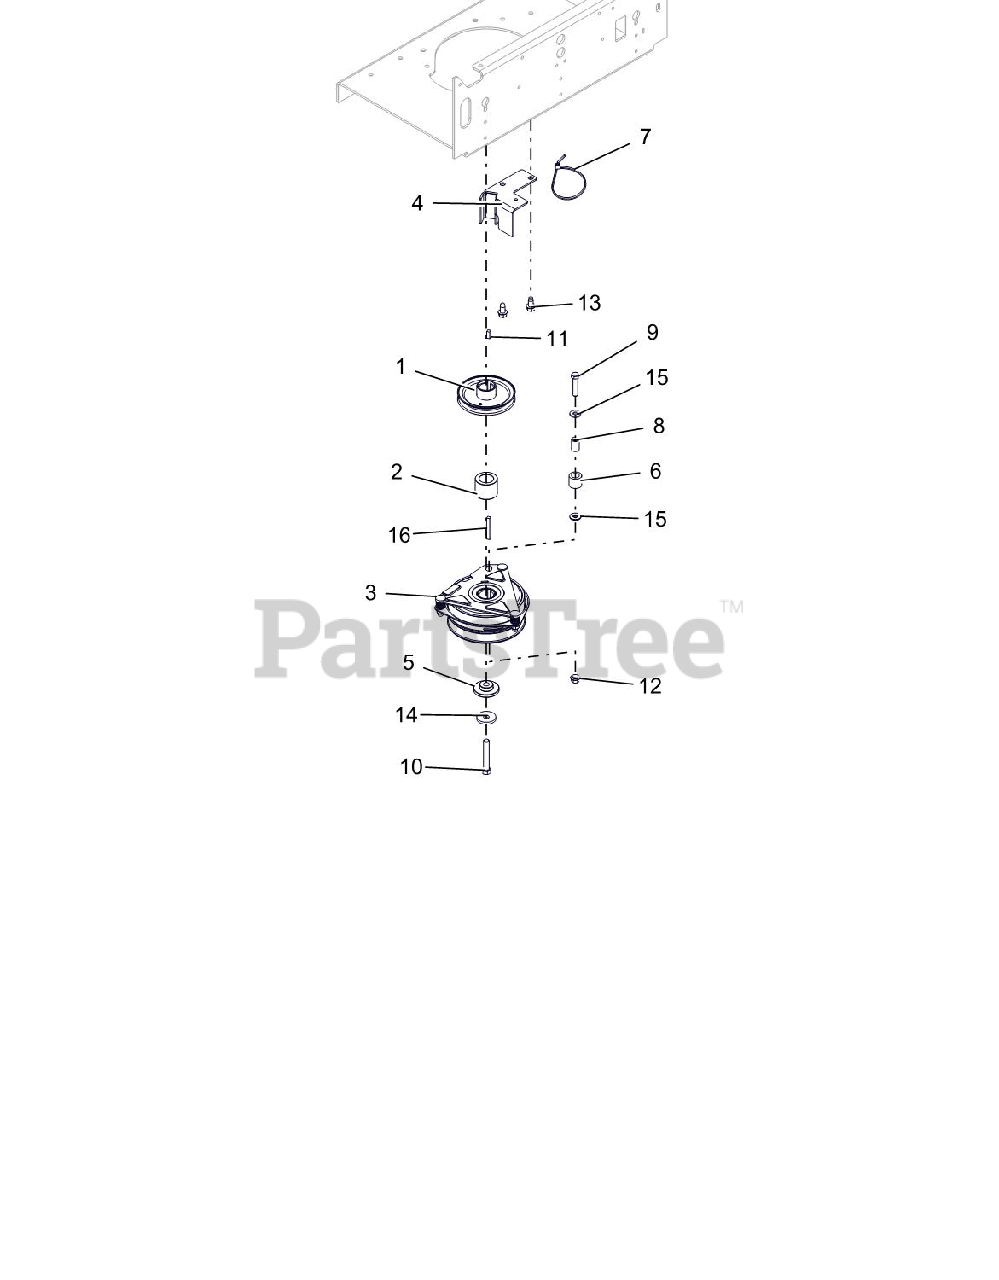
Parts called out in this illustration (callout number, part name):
1	PULLEY, 4.50 OD X 1.127 ENGINE
2	SPACER, 1.125 X 1.75 X 1.40
3	CLUTCH, OGURA GT2.5-FE02
4	CLUTCH STOP WLDMT - BLACK
5	BSHG-FLG .469X1.06X.574X2.0
6	BUMPER,RUBBER .62X1.0X.88 LG
7	CABLE TIE LG 5-1/2
8	BUSH.,S.391X.622X.950 ST
9	@BLT-HEX .38-16X1.75 GR5 YWZC
10	BLT-HEX .44-20X2.75 G8YZNYTORQ
11	KEY-SQ .25X.625X.25 SAE 8630
12	@NUT-LK-TOP-FLG .38-16 YWZC
13	@SCR-TAP .38-16X.75 HWH TR YWZ
14	WASHER, 7/16" SPRING DISK
15	@WSHR-FL-STL.38X.875X.083 YWZC
16	KEY-STR .25X2.0X.25
